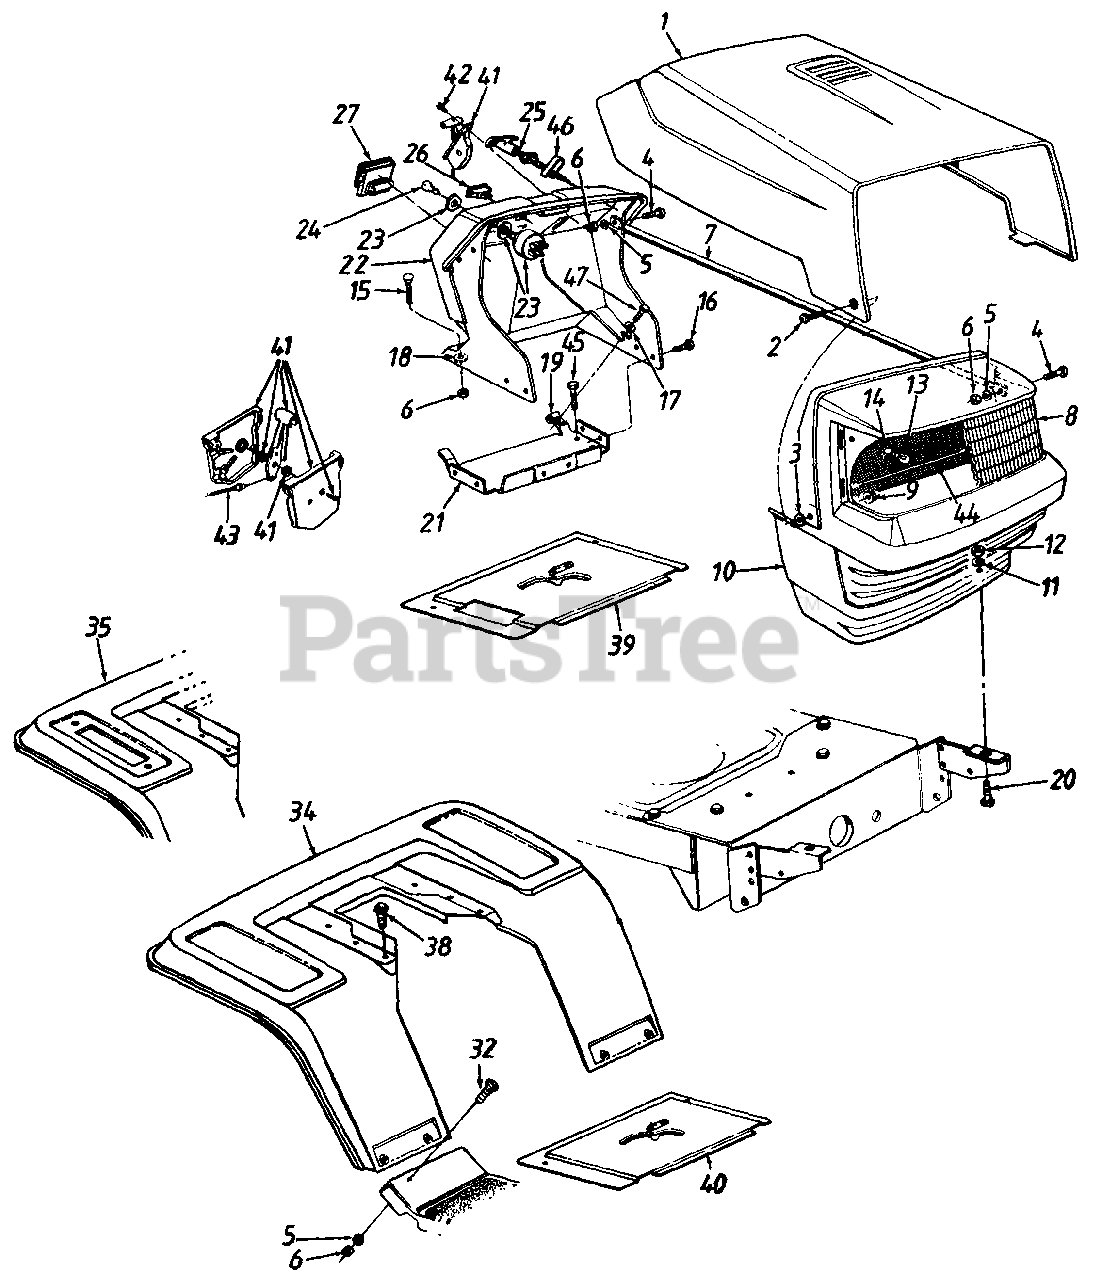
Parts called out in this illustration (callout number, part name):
3	Fl-Wash .28" I.D. x .75" O.D.
4	Hex Bolt 1/4-20 x .62" Lg.
5	L-Wash. 1/4" I.D.
6	Hex Nut 1/4-20 Thd.
8	Headlight Lens
9	Flange L-Nut 1/4-28 Thd.
10	Grille
11	Fl-Wash .344" I.D. x 1" O.D.
12	Hex Nut 5/16-18 Thd.
13	Lamp
14	Socket
15	Carriage Bolt 1/4-20 x .75" Lg.
16	Hex Wash. Hd. TT-Tap Scr. 1/4-20 x .5" Lg.
17	Fl-Wash .281" I.D. x .73" O.D.
18	Bolt Retainer 1/4" I.D.
19	Speed Nut 1/4-20 Thd,
20	Hex Bolt 5/16-18 x .75" Lg.
23	Ignition Switch
24	Ignition Key
25	Choke Control
26	Light Switch
27	Ammeter
32	Truss Mach. Scr. 1/4-20 x .5" Lg.
41	Throttle Box Ass'y.
42	Truss Mach. AB-Tap Scr. #10 x .5" Lg.
43	Throttle Control Wire
44	Grille Reflector Label
45	Hex Wash. Hd. B-Tap Scr. 5/16-18 x .5" Lg.
46	Choke Retainer
47	Hex TT-Tap Scr. 1/4-20 x .75" Lg.
